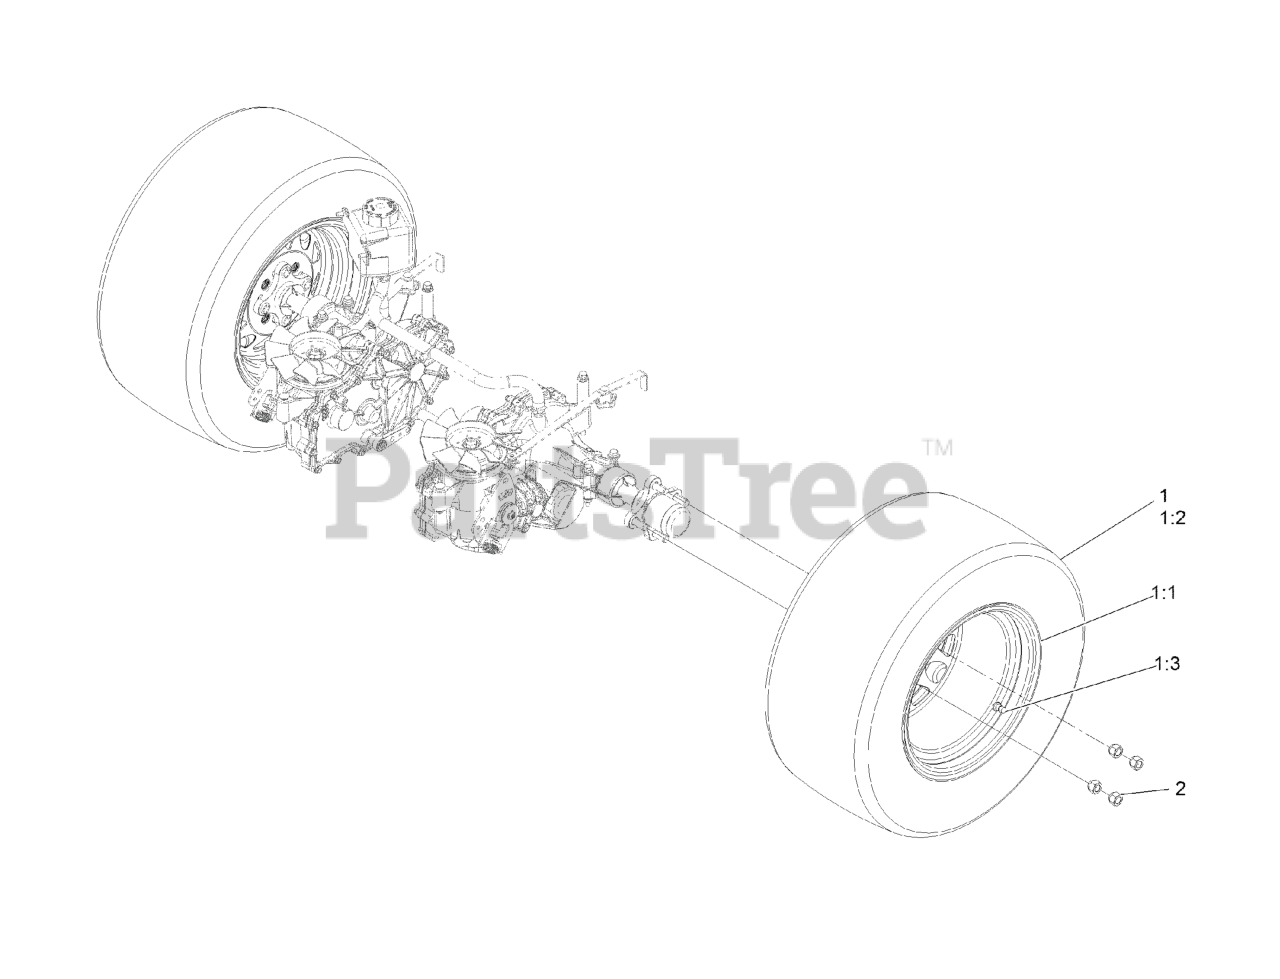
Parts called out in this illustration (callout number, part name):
1	WHEEL AND TIRE ASM
1:2	TIRE 23 X 10.50-12
1:3	VALVE
2	NUT-LUG
